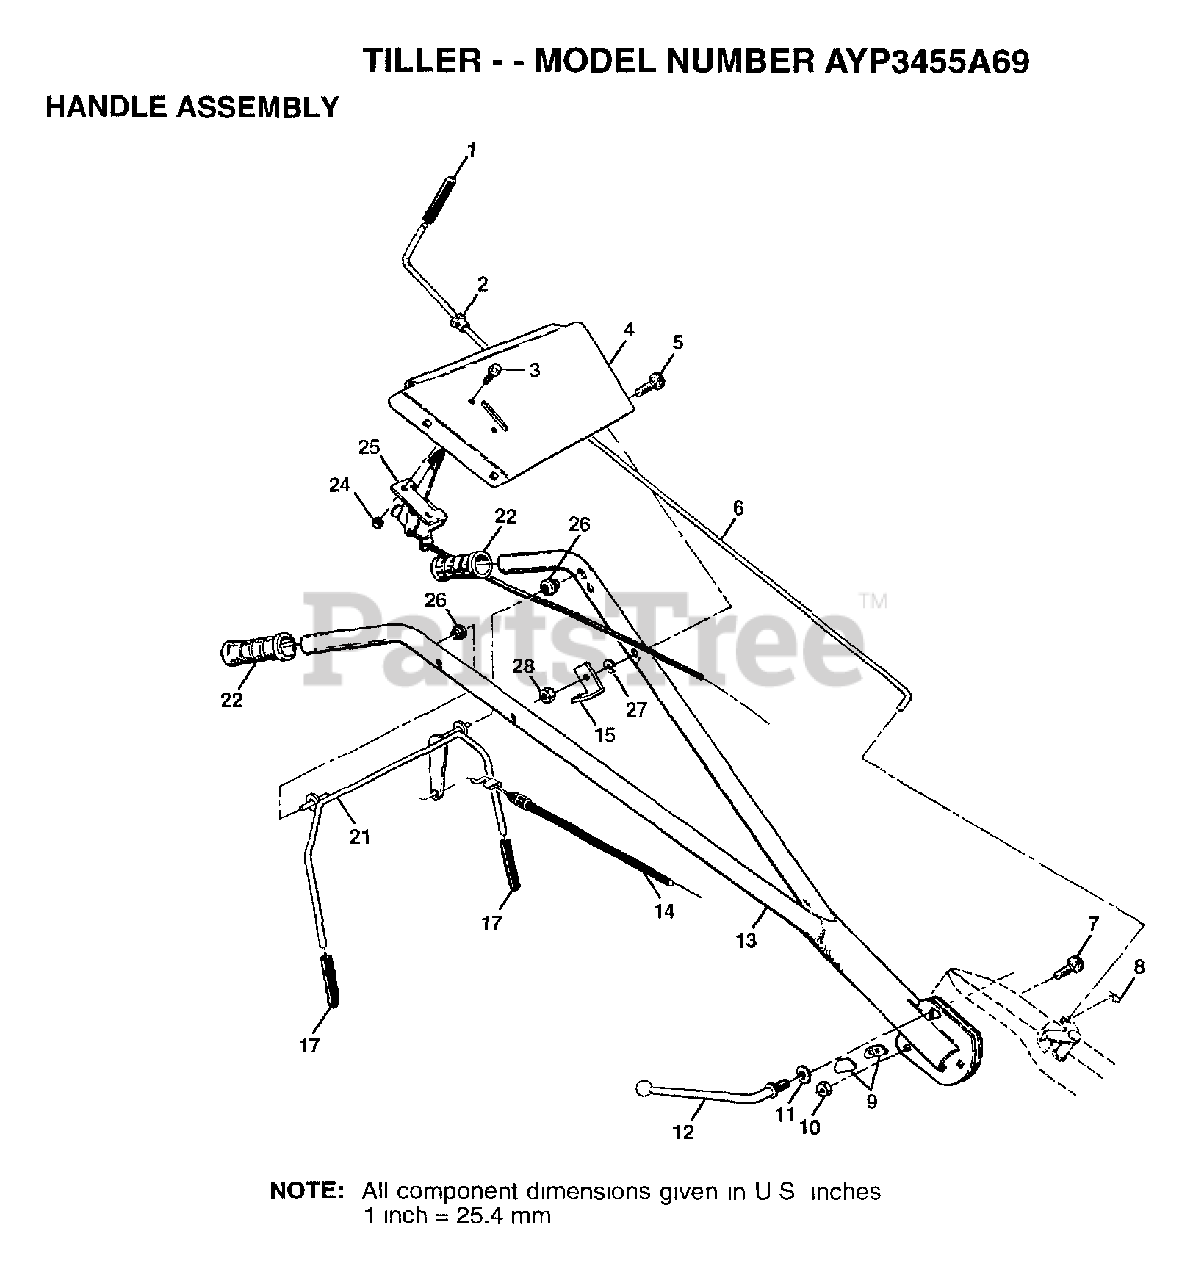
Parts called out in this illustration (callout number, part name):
1	GRIP TI
2	BUSHING
3	SCREW.PNHD.10-24
4	HANDLE BRACKET
5	BOLT CARRIAGE CRT
6	ROD SHIFT CRT
7	BOLT D
8	RETAINER M
9	LOCK CRT
10	LOCKNUT
11	WASHER CRT
12	LEVER LOCK CRT
14	CABLE.CLUTCH.Z-BE
15	BRACKET.CLUTCH.CA
17	GRIP BAR CRT
18	BOLT PIVOT
21	BAR.ASM.CNTRL.VPL
22	"GRIP,HANDLE"
25	"CONT,THROTTLE"
26	GROMMET.HANDLE.V-
27	LOCKWASHER
28	NUT
